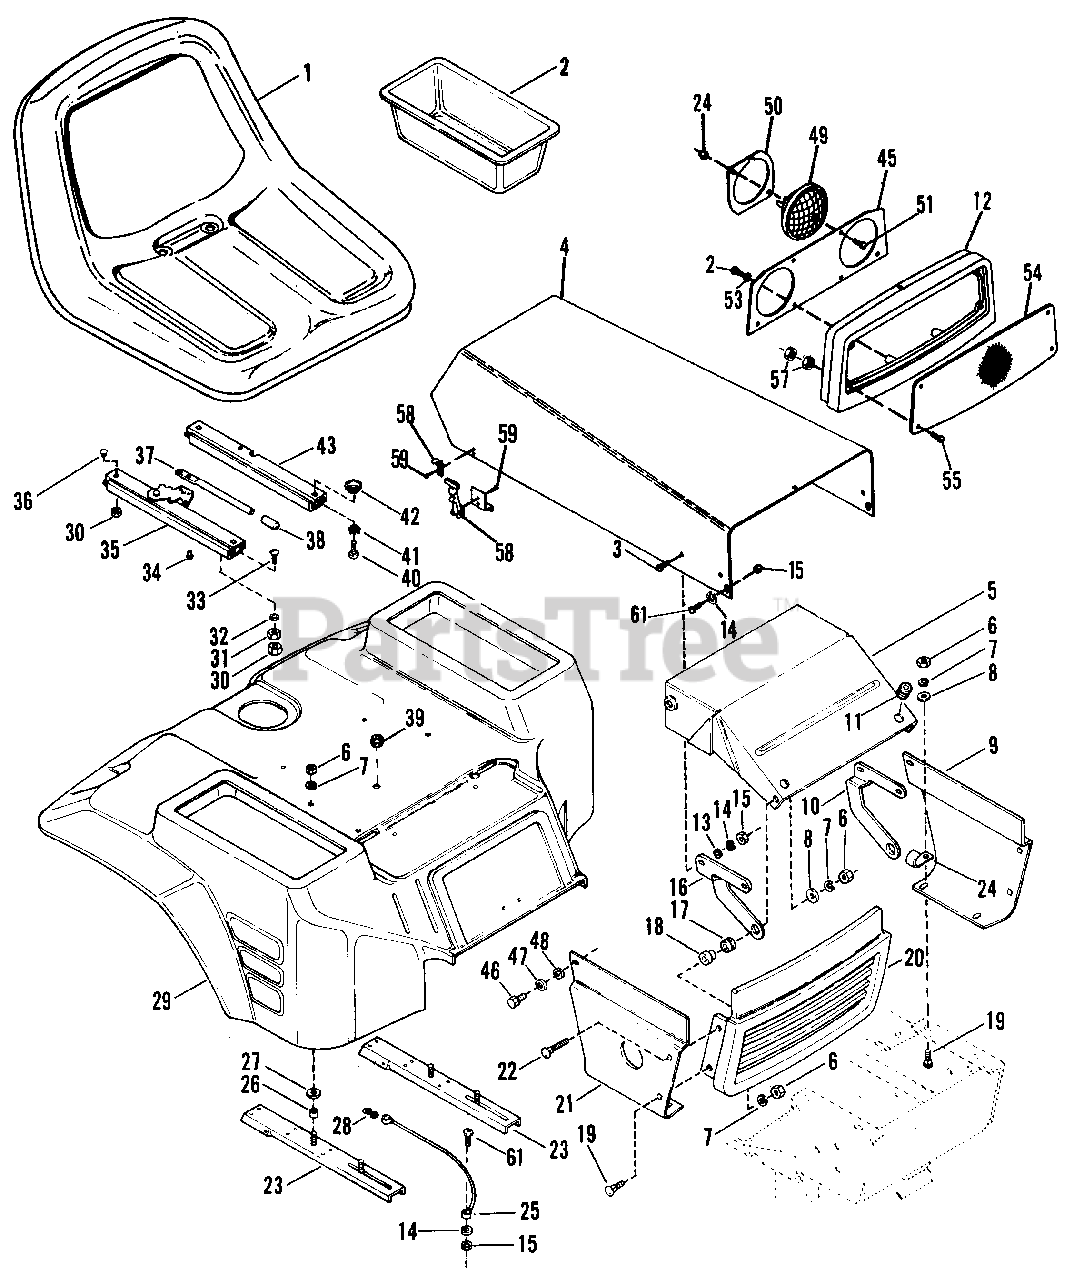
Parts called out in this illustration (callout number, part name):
1	Seat, High Back
2	Tray
3	Bolt, 1/4-20 x .75 Rd Hd Sq Nk
4	Hood, Tractor
5	Muffler Shield
6	Nut, Hex 3/8-16
7	Washer, Lock 3/8 Reg.
8	Washer, Flat .438 x 1.000 x .083
9	Panel, Side L.H.
10	L.H. Hood Hinge
11	Grommet
12	Bezel, Headlight
13	Washer, Flat .281 x .625 x .065
14	Washer, Lock 1/4 Reg.
15	Nut, Hex 1/4-20
16	R.H. Hood Hinge
17	Grommet
18	Spacer
19	Bolt, 3/8-16 x 1.00 Rd Hd Sq Nk
20	Casting, Grille
21	Panel, Side R.H.
22	Bolt, 3/8-16 x 2.00 Rd Hd Sq Nk
23	Seat Support
24	Nut, Lock 1/4-20
25	Cable
26	Spacer
27	Washer, .380/.390 x .750 x .125
28	"S" Hook
29	Rear Deck
30	Nut, Lock 5/16-18
31	Nut, Hex 5/16-18
32	Washer, Lock 5/16 SP
33	Screw, Cap BTHD 5/16-18 x .875
34	Pop Rivet
35	Seat Slide, R.H.
36	Screw, Cap BTHD 5/16-18 x .50
37	Seat Slide Handle
38	Grip
39	Grommet
40	Screw, Mach. 5/16-18 x 1.00 Rd Hd
41	Washer, Lock 5/16 Ext.
42	Spacer
43	Seat Slide, L.H.
44	Clip
45	Panel, Headlight Reflector
46	Screw, Machine 5/16-18 x .75
47	Washer, Flat .375 x .734 x .065
48	Washer, Lock 5/16 Int. Tooth
49	Headlight
50	Headlight Retainer Ring
51	Bolt, Hex 1/4-20 x 1.25
52	Screw, Tapping 1/4-20 x .625
53	Washer, Lock 1/4 Ext.
54	Panel, Headlight Lens
55	Screw, Mach. 10-24 x .75 PHD
57	Nut, Hex 10-24
58	Latch, Flexible
59	Rivet, Pop Domed 1/8 x .294
61	Screw, 1/4-20 x .75 Torx Slotted Ph Pl
NS	Decal, Side Stripe R.H. and L.H.
NS	Decal, 7173-H
NS	Decal, Gravely Logo
NS	Decal, Maintenance Instructions
